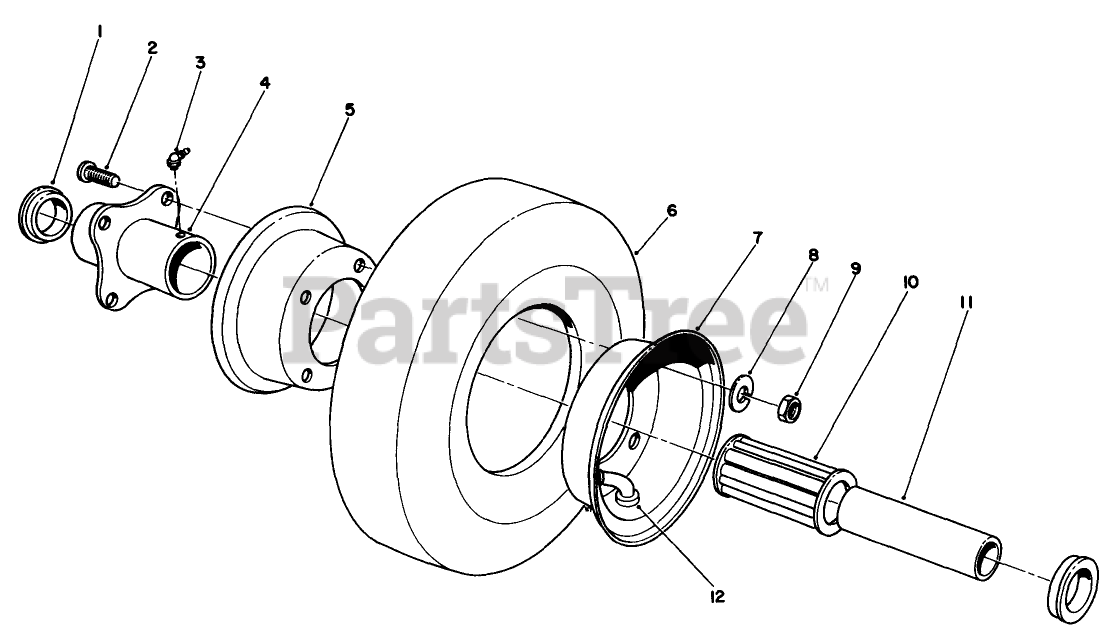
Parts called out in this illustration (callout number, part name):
1	RETAINER
2	WHEEL BOLT
3	FITTING-GREASE
4	HUB - CENTERED
5	WHEEL HALF-FEMALE
6	TIRE 8"(4-PLY)
7	WHEEL HALF-MALE
8	SCREW-HH
9	NUT-HEX
10	ROLLER BEARING
